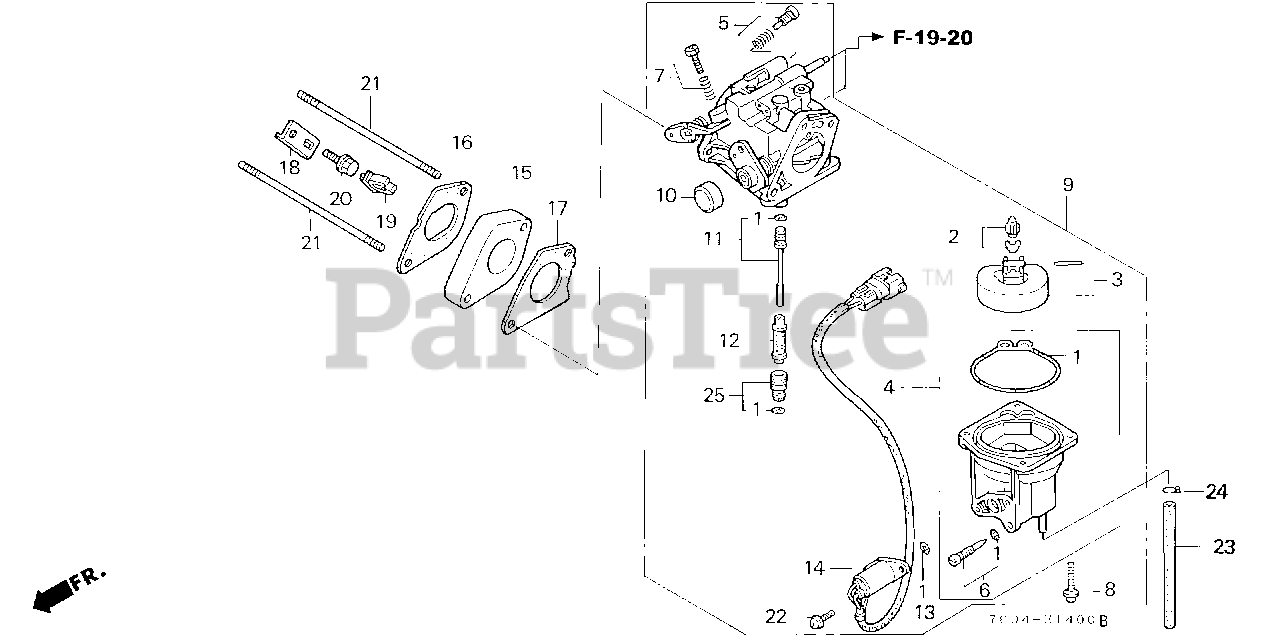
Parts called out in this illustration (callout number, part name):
1	GASKET SET
2	VALVE SET, FLOAT
4	CHAMBER SET, FLOAT
6	SCREW SET, DRAIN
8	SCREW-WASHER
9	CARBURETOR ASSY. (BG19C A)
10	CAP, CHOKE LEVER DUST
11	JET SET (#48)
12	NOZZLE, MAIN
13	O-RING (5.8X1.9)
14	VALVE ASSY., SOLENOID
15	INSULATOR, CARBURETOR
16	GASKET, INSULATOR
17	GASKET, CARBURETOR
18	BRACKET, HARNESS CLIP
19	CLIP B, AIR TEMPERATURE SWITCH WIRE
20	BOLT, FLANGE (6X14)
21	BOLT, STUD (6X113)
22	SCREW-WASHER (5X12)
23	BULK HOSE, FUEL (4.5X3000) (4.5X380)
24	CLIP, TUBE (B8)
25	JET SET, MAIN (#92)
25	JET SET, MAIN (#95)
25	JET SET, MAIN (#98)
